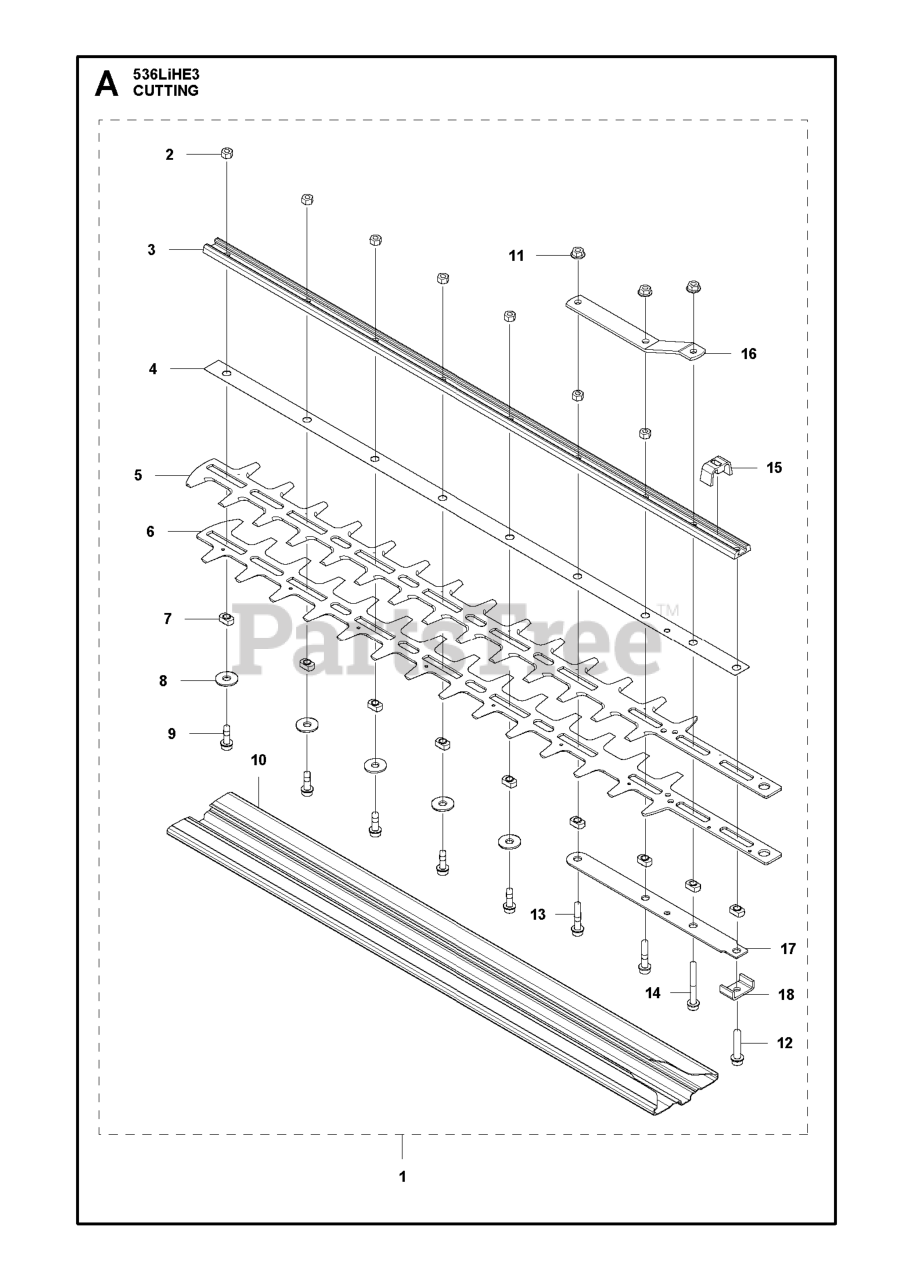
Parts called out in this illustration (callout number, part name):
1	CUTTING DECK ASSY
2	HEXAGON NUT ISO 4032-M5-10
3	BAR CUTTING DECK 55
4	WEAR PLATE CUTTING DECK 55
5	BLADE ASSY 55
6	BLADE ASSY 55
7	SPACER CUTTING DECK
8	WASHER 6,4X18X1,5
9	SCREW M5X16 T25
10	TRANSPORT GUARD CUTTING DECK 5
11	HEXAGON NUT FLANGE M5 8 ZN/FE
13	SCREW IHSCFM M5X25 10.9 ZN/FE
16	SUPPORT CUTTING DECK
18	BRACKET CUTTING DECK
